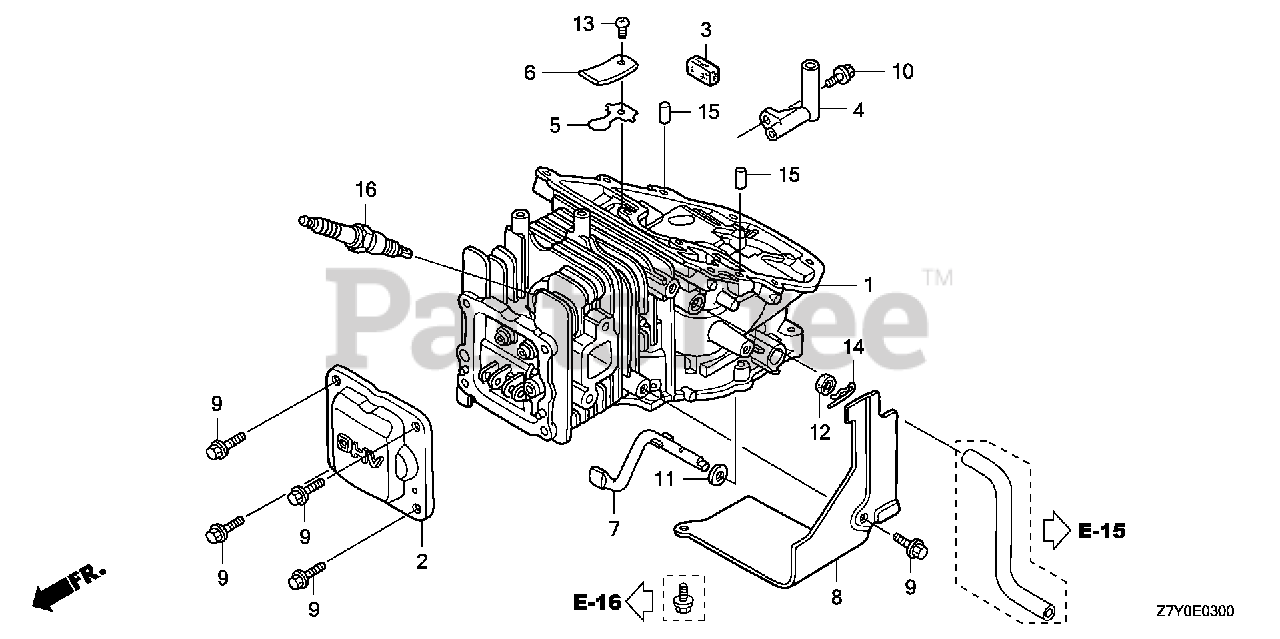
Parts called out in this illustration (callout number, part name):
2	COVER, HEAD
3	FILTER, BREATHER
4	PIPE, BREATHER
5	VALVE, OIL OUTLET
6	PLATE, STOPPER
7	SHAFT, GOVERNOR ARM
9	BOLT, FLANGE (5X12)
10	BOLT (4X10)
11	WASHER (5.2X9)
12	OIL SEAL (5X11X5)
13	SCREW, PAN (3X5)
14	PIN, LOCK (6MM)
15	ROLLER (6X14.8)
15	ROLLER (6X15)
16	SPARK PLUG (U14FSR-UB)
16	SPARK PLUG (CR4HSB) (NGK)
16	SPARK PLUG (CR5HSB) (NGK)
